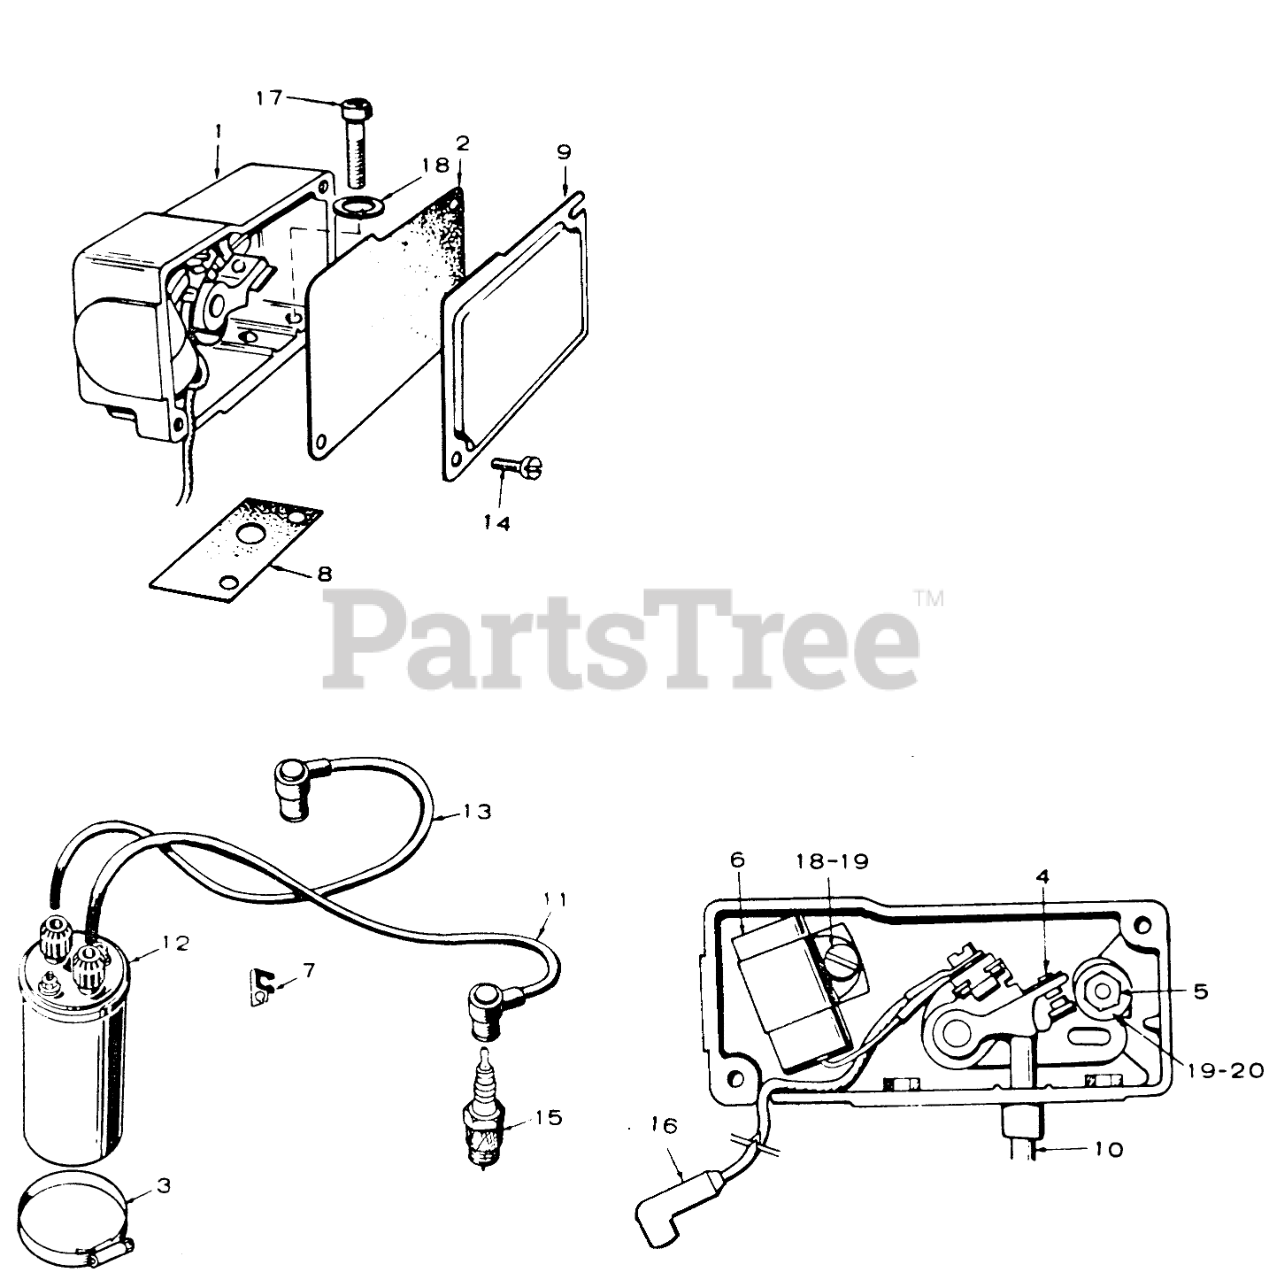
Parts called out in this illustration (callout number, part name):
25	CRANKSHAFT
26	Bolt 1/4-20 X 1/2 Whizlock
27	Locking Screw 5/16-18 X 1/2
28	Crankshaft Key-PTO Side
29	Spacer,Governor Flyball
30	Plate,Governor Flyball
